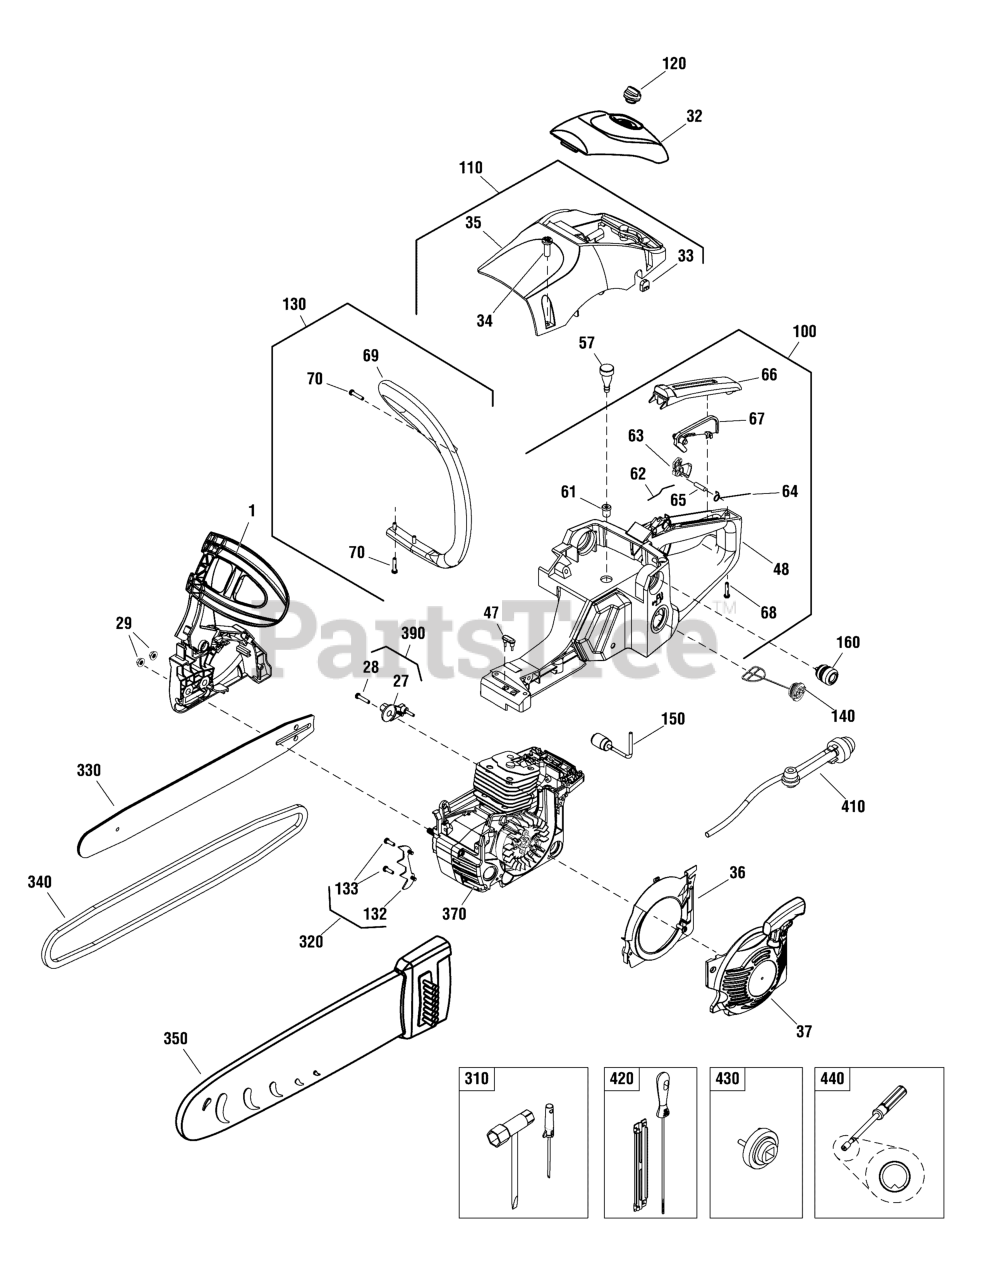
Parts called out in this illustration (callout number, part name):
1	CHAIN BRAKE ASSEMBLY, Pewter
1	CHAIN BRAKE ASSEMBLY, Silver
27	SHIELD, Chain
29	NUT, M8
32	COVER, Air Filter, Black
32	COVER, Air Filter, Blue
33	GUIDE SET, Idle Adjusting
35	COVER PLATE, Upper
36	COVER, Guide Flow
37	STARTER ASSEMBLY, Pewter
37	STARTER ASSEMBLY, Silver
47	SHOCK, Rubber
48	BASE ASSEMBLY
57	BALANCER ASSEMBLY
61	GROMMET
62	ROD, Throttle
63	TRIGGER
64	SPRING, Torsion, Trigger
66	COVER, Rear Handle
67	PRESENCE TRIGGER
69	HANDLE ASSEMBLY, Front
100	HANDLE ASSEMBLY, Rear, Black
100	HANDLE ASSEMBLY, Rear, Silver
110	COVER ASSEMBLY, Upper, Black
110	COVER ASSEMBLY, Upper, Blue
120	KNOB, Air Filter
130	HANDLE ASSEMBLY, Front
132	BUMPER, Spiked
140	FUEL CAP ASSEMBLY
150	FUEL FILTER ASSEMBLY
160	SHOCK BUMPER ASSEMBLY
310	TOOL PACK
320	BUMPER ASSEMBLY
330	BAR, Oregon, 18"
340	CHAIN, Oregon, 18" - 0.325"
350	BAR COVER ASSEMBLY
370	SHORT ENGINE, 45cc
390	CHAIN CATCH ASSEMBLY
410	PRIMER BULB
420	* FILE & GUIDE PACK, 3/16
430	* TOOL, Clutch Removal
440	* TOOL, Carburetor Adjustment
